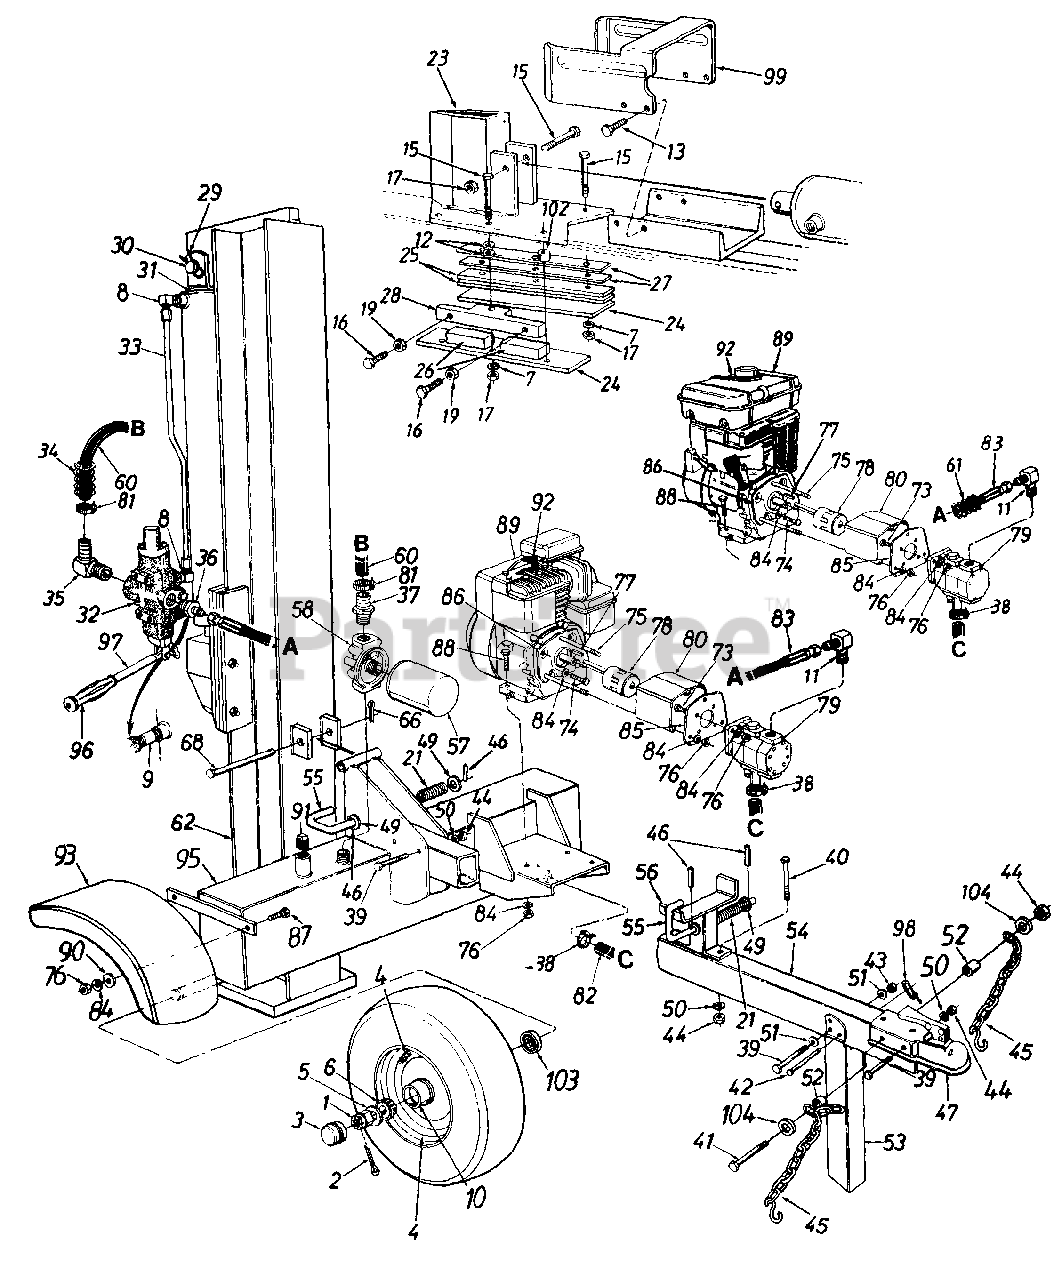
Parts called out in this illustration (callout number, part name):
1	Slotted Nut 3/4-16 Thd.
2	Cotter Pin 5/32" Dia.
3	Hub Cap
5	Fl-Wash .76" I.D. x 1.5" O.D.
6	Bearing Cone
7	L-Wash. 1/2" I.D.
8	90 Deg. Solid Male Adapter
9	Pipe Nipple 1/2 NPT
10	Bearing Cup
11	90 Deg. Male Adapter
12	Fl-Wash .531" I.D. x .94" O.D.
13	Hex Cap Scr. 3/8-16 x 1" Lg.
15	Hex Bolt 1/2-20 x 2.75" Lg. (Grade 8)
16	Hex Bolt 3/8-24 x 1.5" Lg.
17	Hex L-Nut 1/2-20 Thd.
19	Hex Jam Nut 3/8-24 Thd. (Grade 5)
21	Comp. Spring 4" Lg.
29	External Cotter Pin
30	Cylinder Mounting Pin
33	Metal Pressure Tube
34	Hose Guard
35	Return Elbow
36	Adapter
37	3/4" Hose Barb.
38	Hose Clamp
39	Hex Bolt 3/8-16 x 3" Lg. (Grade 8)
40	Hex Bolt 3/8-16 x 4" Lg.
41	Hex Bolt 3/8-16 x 4.25" Lg. (Grade 5)
42	Clevis Pin 5/16 x 2.5" Lg.
43	Hex L-Nut 3/8-16 Thd.
44	Hex Nut 3/8-16 Thd.
45	Chain - Tow Hitch
46	Roll Pin
47	Hitch Coupler
49	Fl-Wash .635" I.D. x .93" O.D.
50	L-Wash. 3/8" I.D.
51	Fl-Wash .406" I.D. x .75" O.D.
52	Spacer.44" Lg.
55	Locking Rod
57	Fllter Element
58	Fllter Head
60	Return Hose 3/4" I.D. x 44" Lg.
61	Hose Guard
68	Hinge Pin 1/2 x 4.8" Lg.
73	Hex Bolt 5/16-24 x 1" Lg.
74	Hex Bolt 5/16-24 x .62" Lg.
75	Hex Bolt 5/16-24 x 4" Lg.
76	Hex Nut 5/16-24 Thd.
77	Sq. Key 3/16" x .75"
78	Flexible Coupling
79	Gear Pump
80	Coupling Shield
81	Hose Clamp 5/8"
82	Suction Hose
83	High Pressure Hydraulic Hose 48"
84	L-Wash. 5/16" I.D.
87	Hex Bolt 5/16-24 x .75" Lg.
88	Hex Bolt 5/16-24 x 1.75" Lg.
89	Engine
90	Fl-Wash .344" I.D. x .875" O.D.
91	L-Vent Pipe Plug
92	Spark Plug Boot
96	Grip
97	Control Handle
98	Spring Pin
102	Spacer 1/2" I.D. x .86" Lg.
103	Bearing Seal Only
104	Fl-Wash. 3/8" I.D. x .87" O.D.
